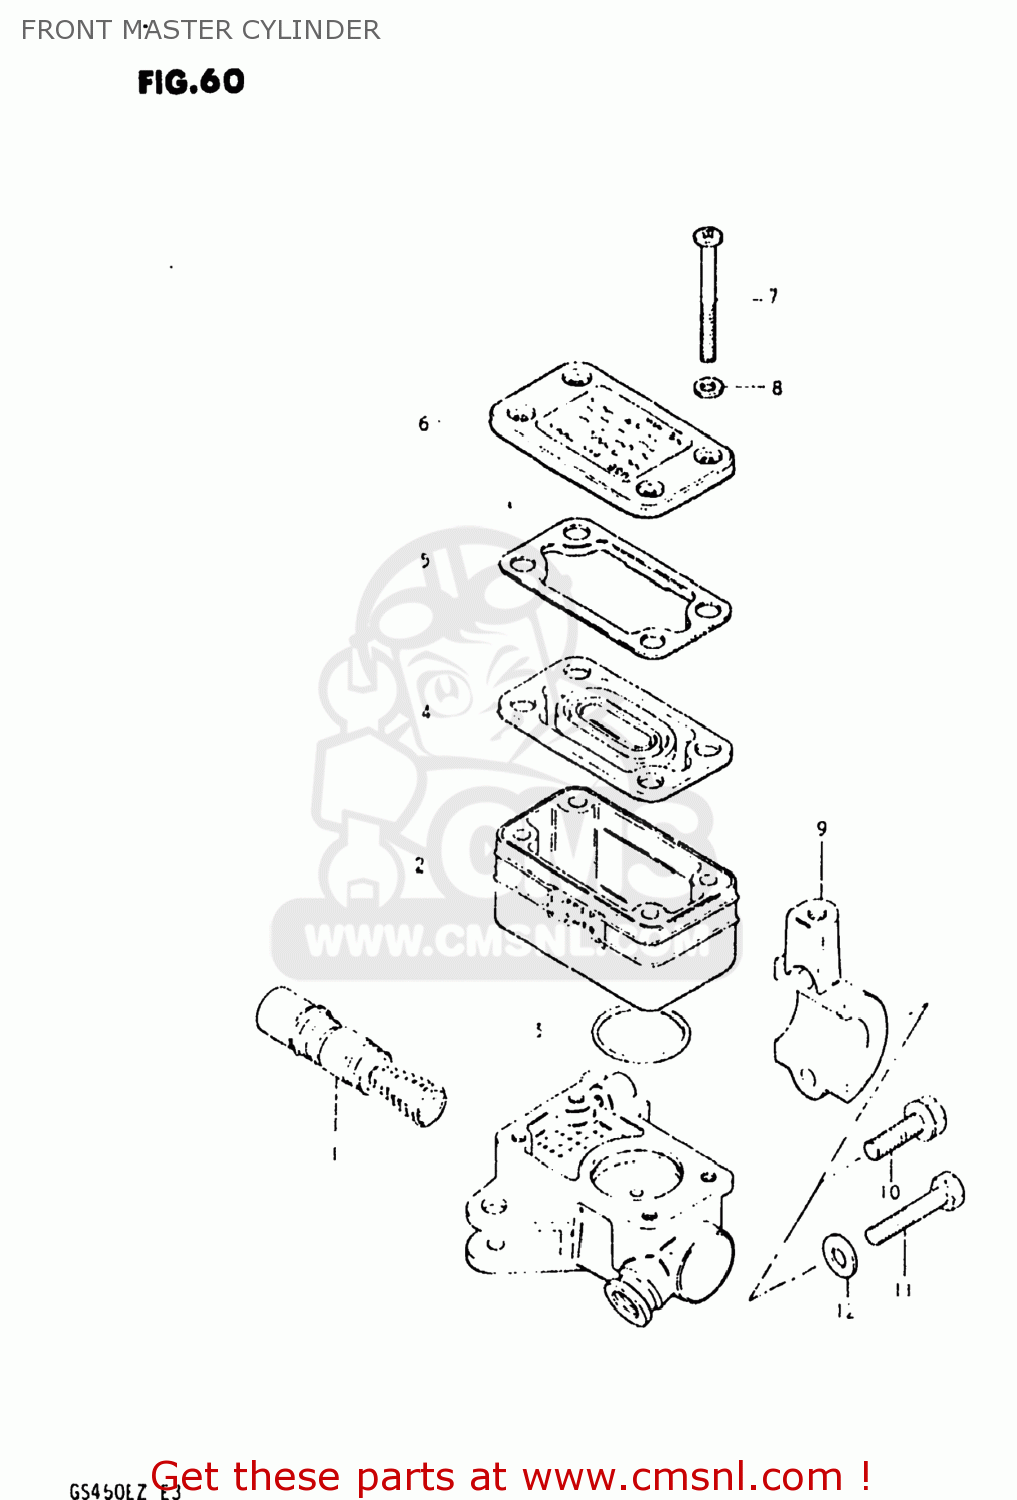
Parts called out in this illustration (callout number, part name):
0	CYLINDER ASSEMBLY,MASTER
1	PISTON & CUP SET
2	RESERVOIR
3	O RING
4	DIAPHRAGM
5	PLATE,DIAPHRAGM
6	CAP
7	SCREW
8	WASHER
9	HOLDER
10	BOLT,MASTER CYLINDER H
11	BOLT
12	WASHER
